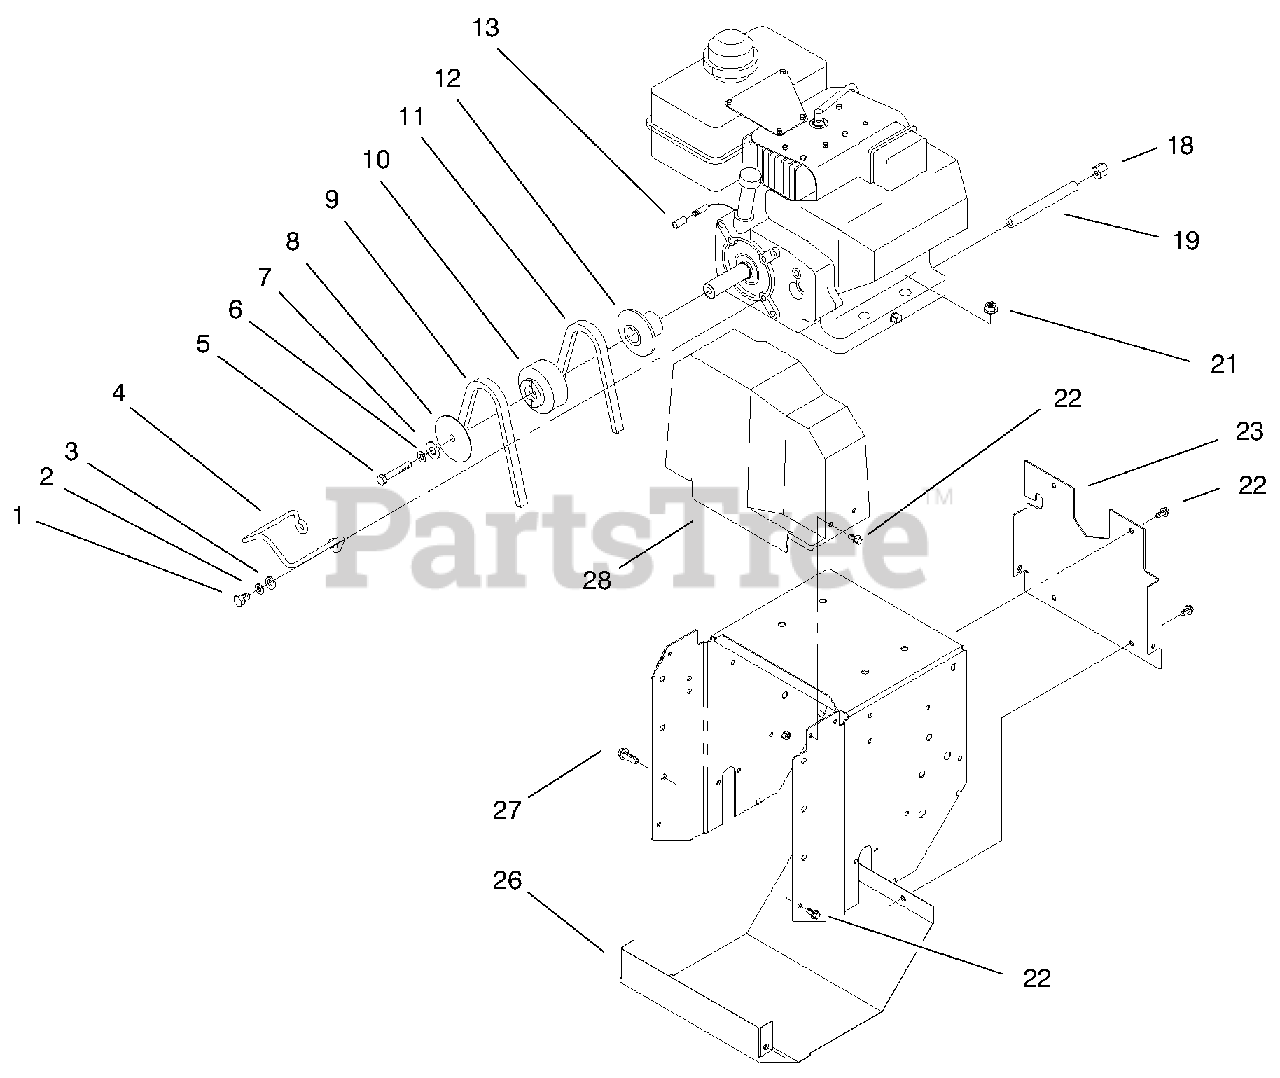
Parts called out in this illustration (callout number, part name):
1	Screw-HH
2	Washer-Lock
3	Washer-Flat
4	Guide-Belt
5	Screw-HH
6	Washer-Lock
7	Washer-Flat
8	Sheave-Half, Impeller
10	Pulley-Engine Center
11	Belt-Traction
12	Sheave-Half, Traction
13	Cap-Wire, Lite
18	Cap-Pipe
19	Nipple-Pipe
21	Nut-Hex, Flange
22	Screw-HH
23	Plate-Back
26	Cover-Lower Traction
27	Screw-HWH
28	Cover-Upper Belt
